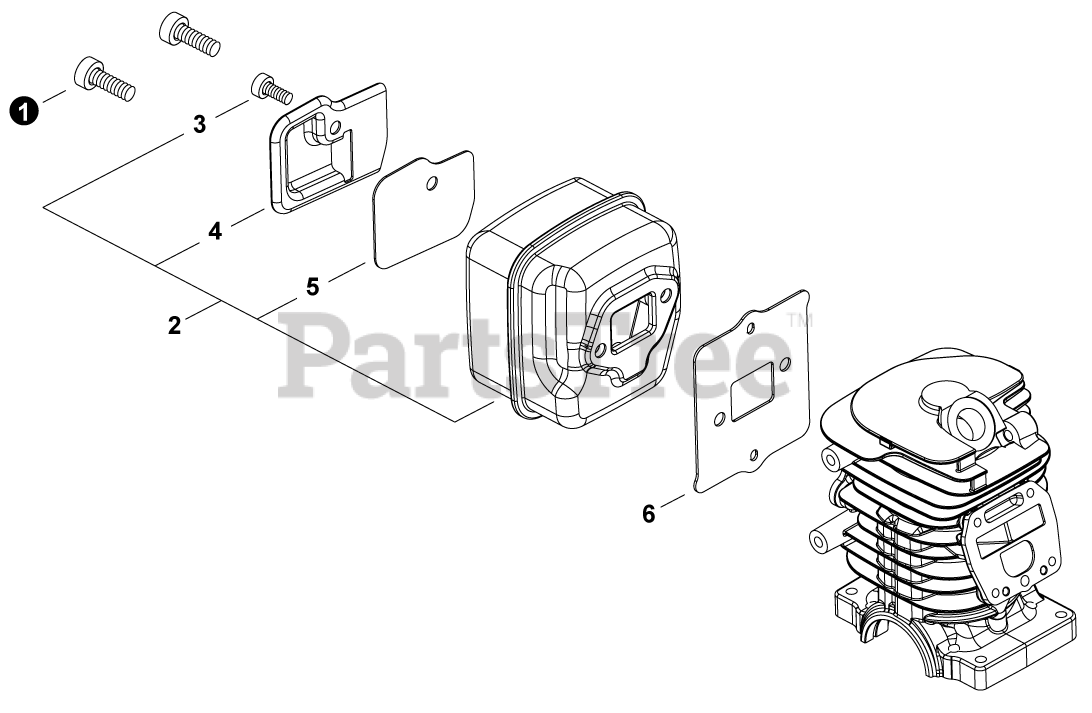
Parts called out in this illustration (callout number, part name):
1	BOLT, TORX 5×16
2	MUFFLER ASSY
3	BOLT, TORX 5×8
4	GUIDE, EXHAUST
5	SCREEN, SPARK ARRESTER
6	GASKET, EXHAUST
